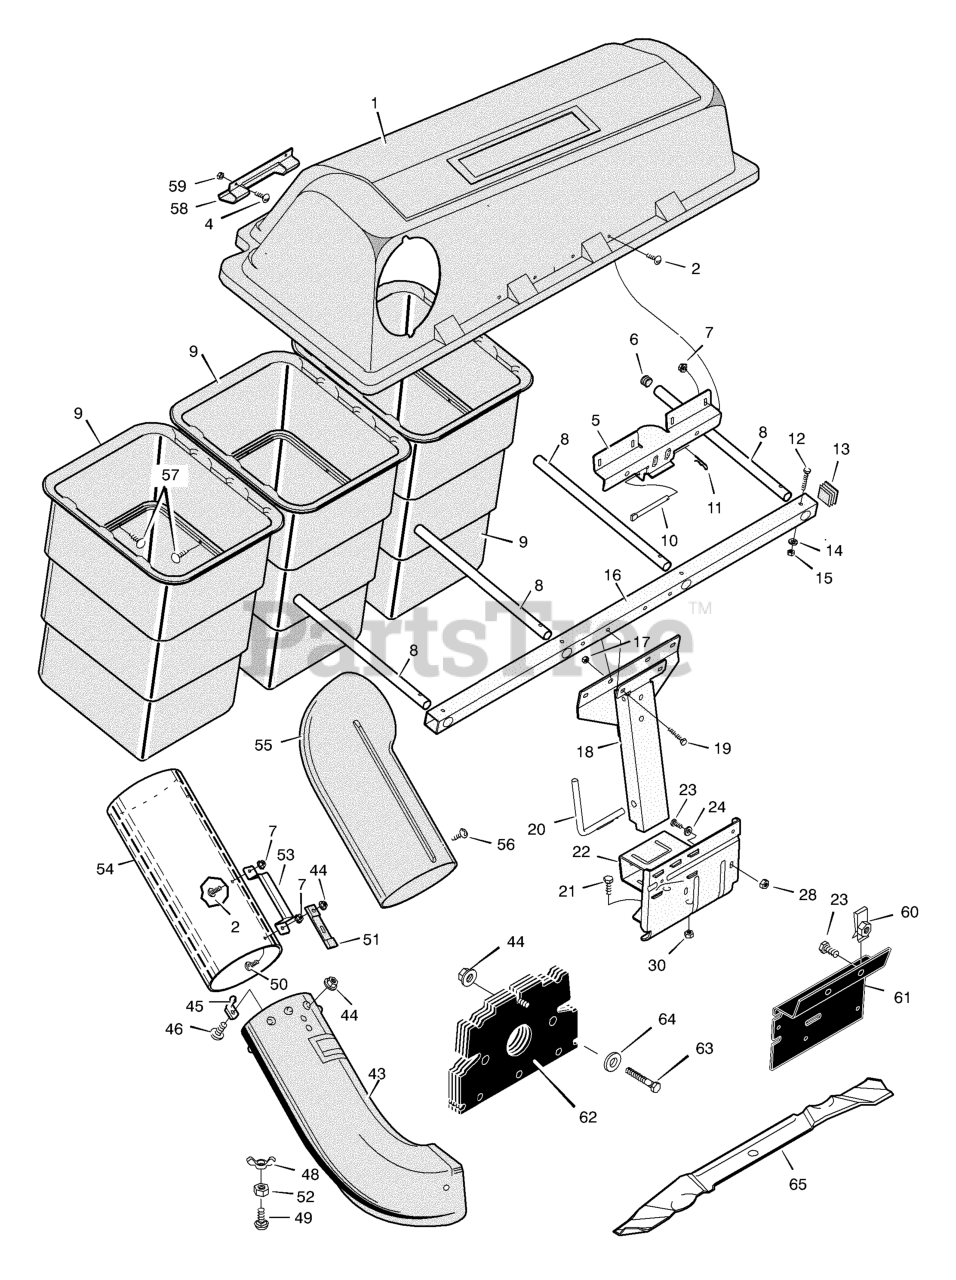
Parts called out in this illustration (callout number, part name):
1	Cover, Bagger
5	Hinge, Bracket
7	Nut, Hex
8	Tube, Container
9	Container
10	Pin, Cover Hinge
11	Pin, Hair
13	Plug
14	Lockwasher
16	Tube, Support
17	Nut
18	Assembly, Channel
20	Pin, Channel Mount
21	Bolt, Hex
22	Assembly, Bagger Mount
23	Bolt, Hex
28	Nut, Super Flange
30	Nut, Hex
43	Extension, Chute
44	Locknut, Flange
45	Pin, Latch
46	Bolt, Carriage
48	Wingnut
49	Bolt, Carriage
51	Latch, Rubber
53	HANDLE, Connect Tube
54	Tube, Connecting
57	Fastener, Panel
58	Handle, Plastic
59	Nut, Hex
61	Bracket, Adapter
62	Weight, Front
65	Blade, Hi-Lift (117cm)
